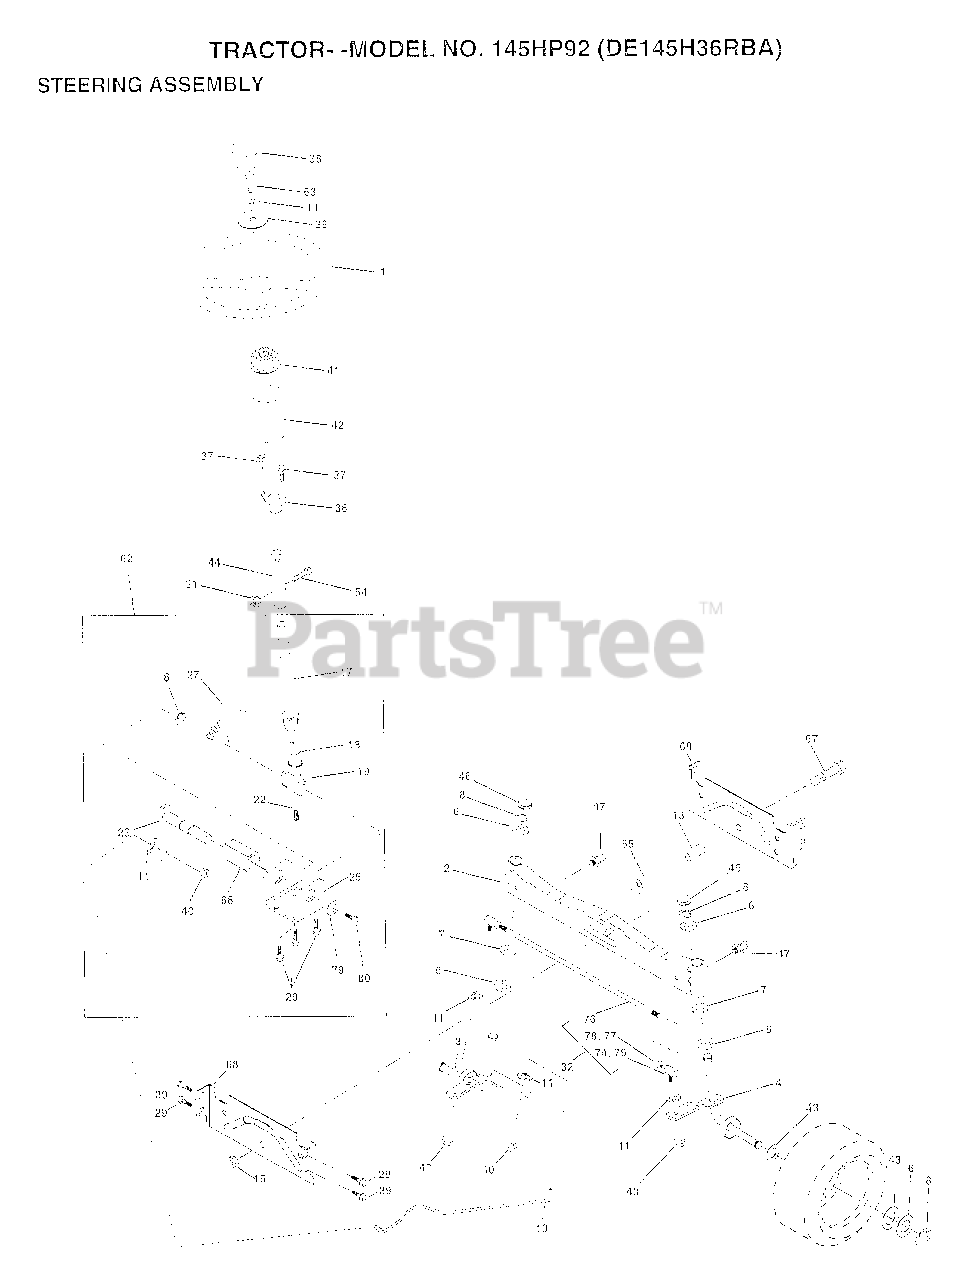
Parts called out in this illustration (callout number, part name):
3	"SPINDLE ASM,LH"
4	"SPINDLE ASM,RH"
5	WASHER .T
6	WASHER
7	WASHER
8	RING
10	LINK.DRAG
11	LOCKWASHER
13	BEARING.FRT.SPACER.AXLE
15	"NUT-LOC,FLANGE LT"
17	SHAFT ASM STEERIN
18	THRUST WASHER
19	SUPPORT.SHAFT.STEER
22	SCREW.HX.WSH.HD
23	SHAFT.ASM.PITMAN
25	BRKT-STEERING
27	GEAR SECTOR
29	SCREW
32	ROD.ASM.TIE.BALL
36	BUSHING.STEERING
37	"SCREW-TT,10-32 FL"
38	CAP WHEEL STEER
39	WASHER T
40	GRIPCO NUT
41	ADAPTER LT
42	BOOT.STEER.PL
43	WASHER
44	EXT SHAFT STEERIN
46	CAP
47	ZERK M
51	NUT
54	BOLT
62	KIT.STEER.ASM
63	BOLT
65	SPACER AXLE
66	"BEARING-ARM,PITMA"
67	BOLT
68	BRACE AXLE
74	JOINT.RH
75	JOINT.LH
77	NUT
78	NUT
79	WASHER
80	BOLT.HX.NYLON3/8-16X3/
